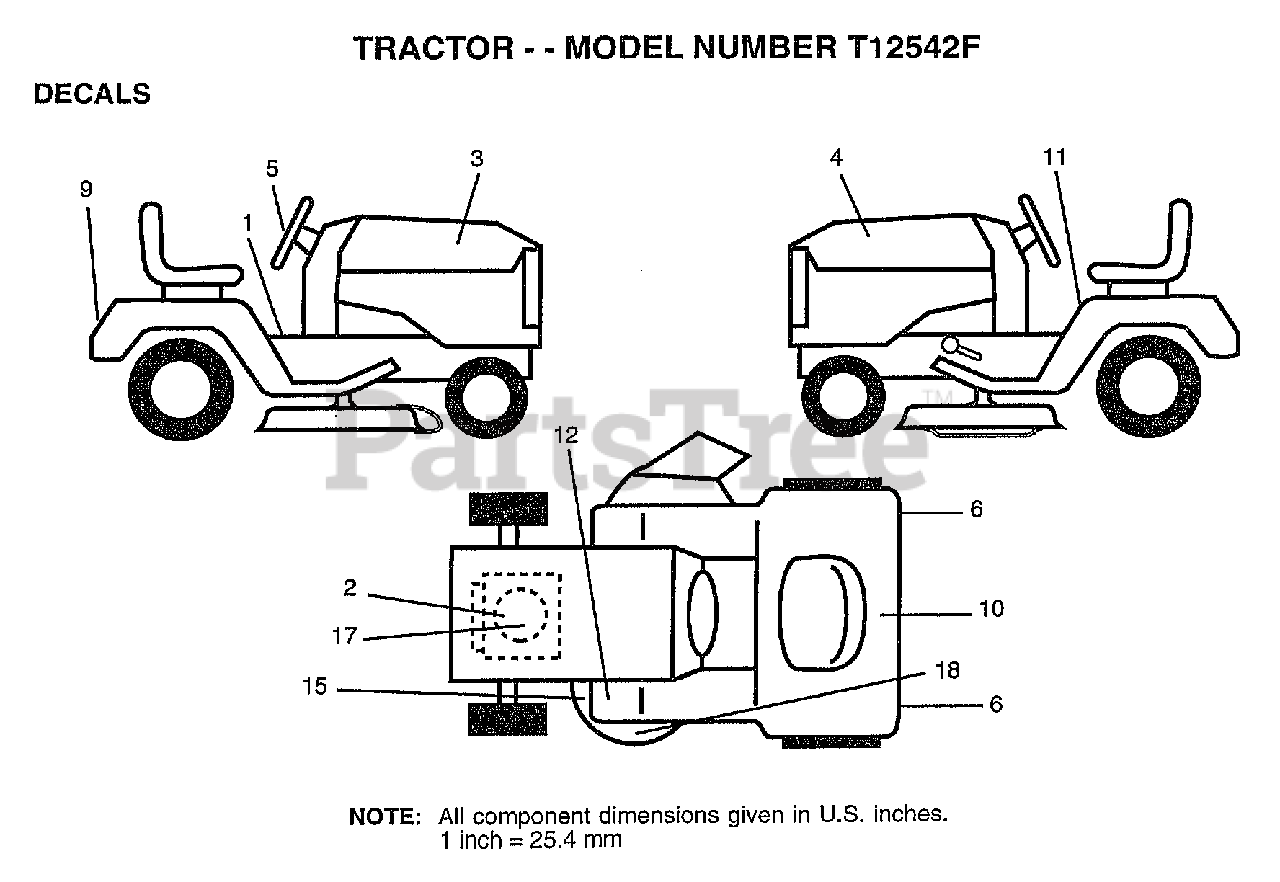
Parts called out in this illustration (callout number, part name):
1	"DECAL DASH,OPER."
2	DECAL, HP ENGINE
3	DECAL.HD.RH.12.5
4	DECAL.HD.LH.12.5
5	"DECAL,STR WHL T"
6	REFLECTOR-TAIL YT
9	DECAL.FENDER
10	DECAL.BATRY.3-3908
11	"DECAL DANGER,FEND"
15	"DECAL-SCHEM,BELT"
